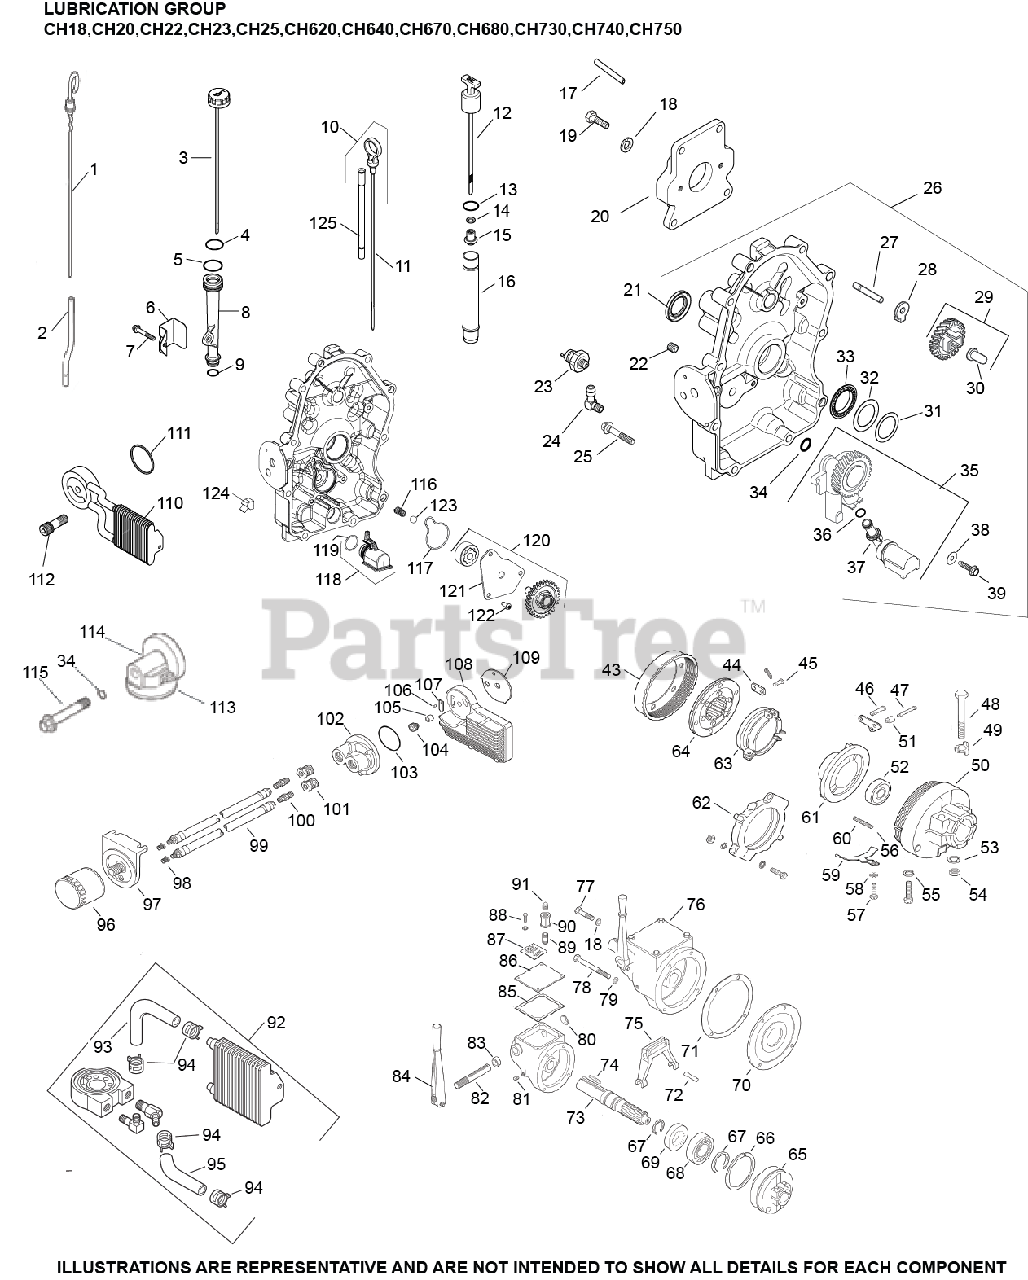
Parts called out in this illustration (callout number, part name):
10	KIT, DIPSTICK/DIPSTICK TUBES
21	SEAL, OIL (KM)-USE 25 032 06-S
22	PLUG, CTSK PIPE 1/8"
23	SENSOR, OIL PSI
25	SCREW, FLG M8X1.25X45
25	SCREW - DISCONTINUED
26	KIT, CLOSURE PLATE USE 24 009 230-S
26	CLOSURE PLATE ASSEMBLY (SERVICE) USE 24 009 237-S
27	SHAFT, GOVERNOR GEAR
28	TAB, LOCKING
29	KIT, GOVERNOR GEAR W/PIN
30	PIN, GOVERNOR REGULATING
35	PUMP ASSEMBLY, OIL-USE 24 393 53-S
36	O-RING, OIL PICK-UP
96	OIL FILTER
104	NIPPLE, OIL FILTER
110	KIT, OIL COOLER
111	O-RING, OIL COOLER
116	SPRING, COMPRESSION
117	SEAL, OIL PUMP COVER
118	PICK-UP ASSEMBLY, OIL
119	O-RING, OIL PICK-UP
120	PUMP ASSEMBLY, OIL
121	COVER, OIL PUMP
122	SCREW, BUTTON HEAD
123	PRESSURE RELIEF BALL
